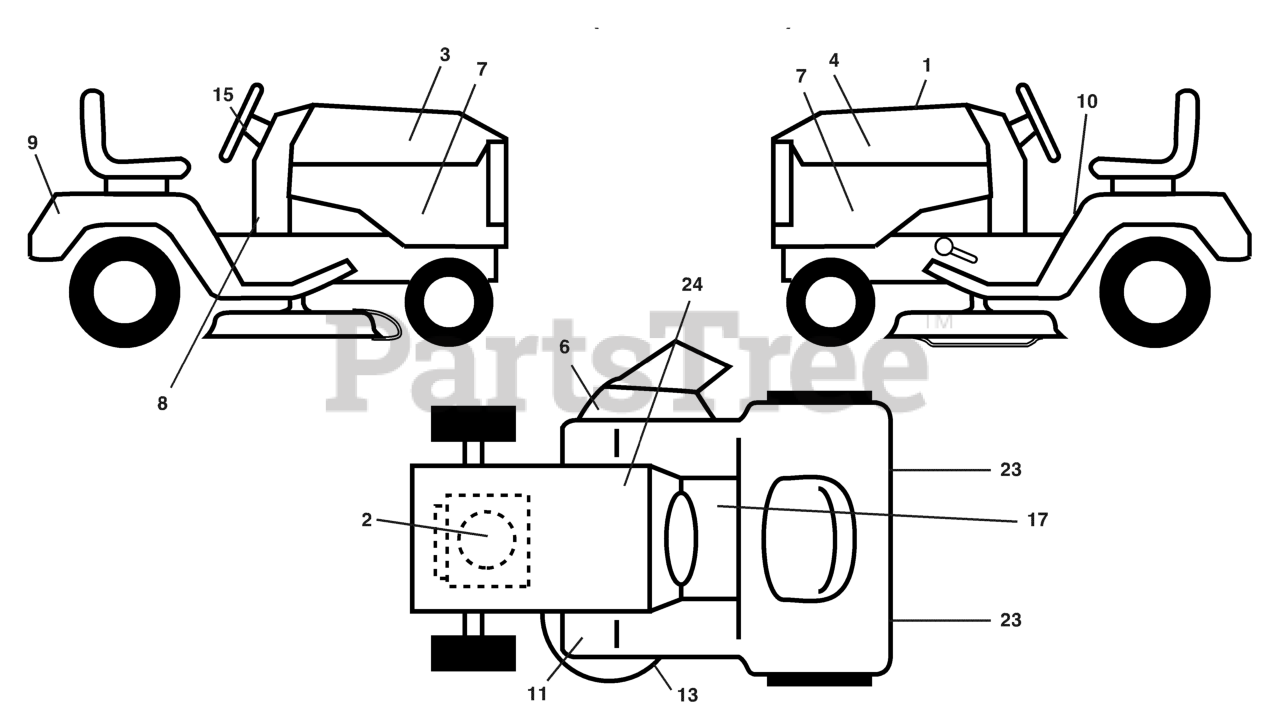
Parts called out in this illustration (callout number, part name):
1	DECAL, REPL. PARTS
2	DECAL, ENGINE LOGO
3	DECAL, HOOD RH
4	DECAL, HOOD LH
6	DECAL.WARN.KEEP.HAND.AWAY
7	DECAL, SIDE PANEL
8	DECAL, DASH
9	DECAL, FENDER
10	DECAL FENDER DANGER
11	DECAL, FOOTREST
13	DECAL V-BELT SCHEMATIC
15	DECAL.WHEEL.STEERING.HUSQ.PERM
17	DECAL PARK BRAKE
23	REFLECTOR-TAIL YT
24	DECAL BTRY SYMBOLS
24	DECAL.BYPASS.FENDER.CRD.LT.YT
24	DECAL HANDLE LIFT
